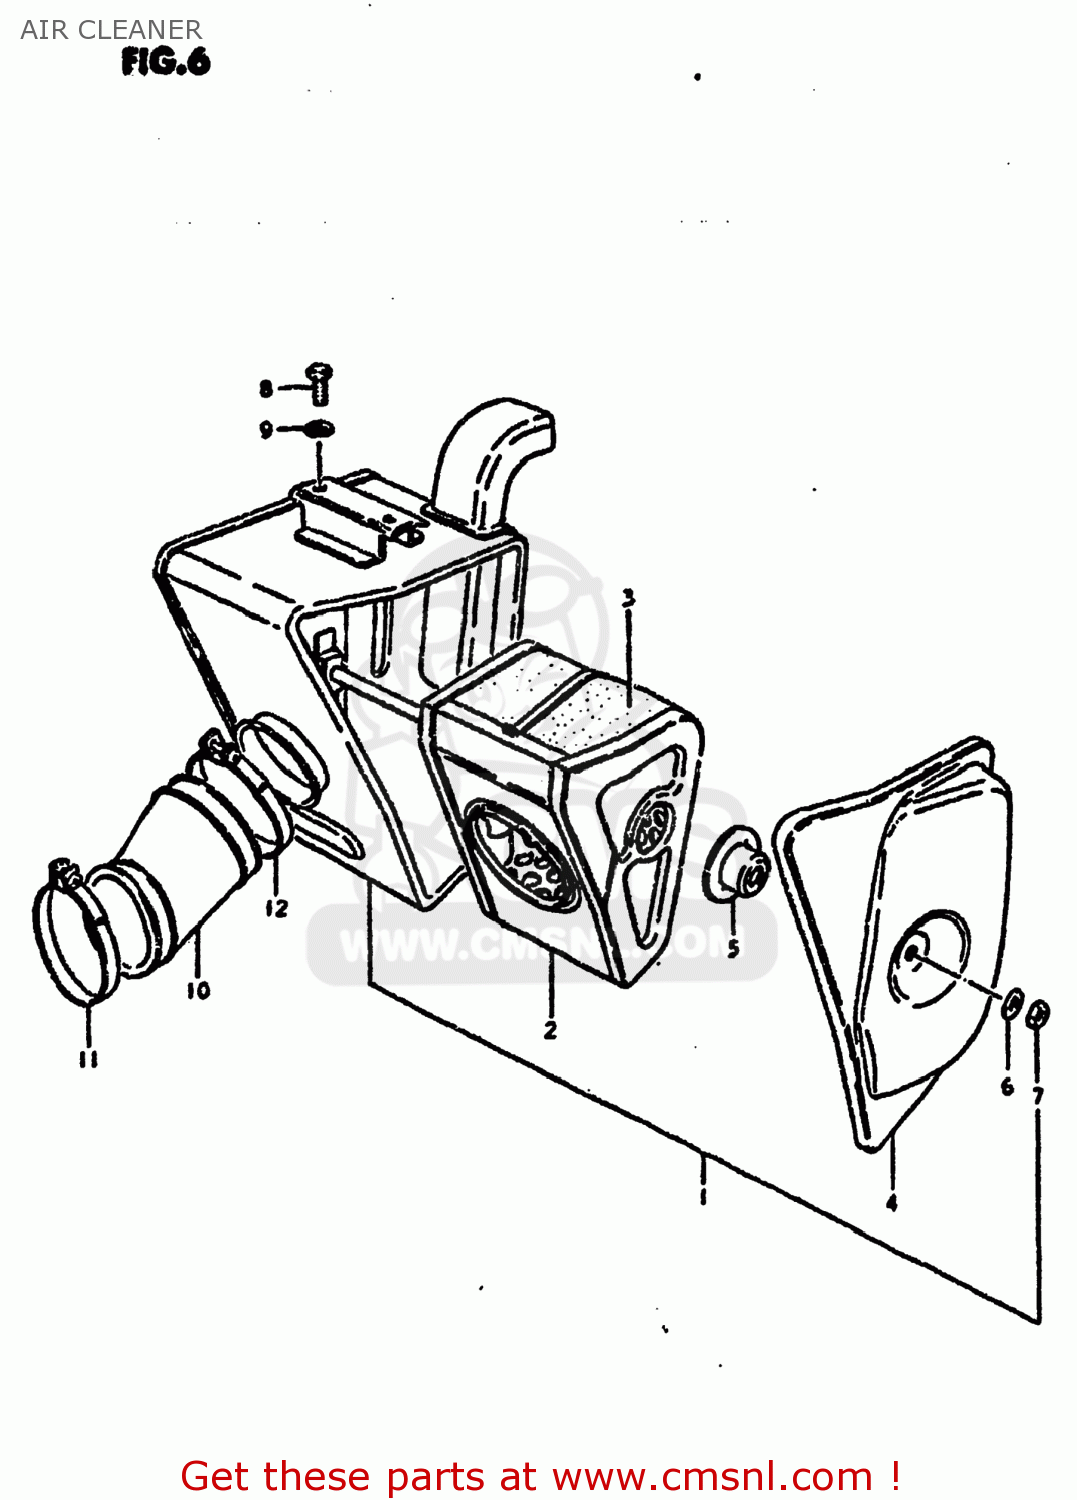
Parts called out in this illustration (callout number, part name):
1	CLEANER ASSEMBLY,AIR
2	FILTER ASSY,AIR CLEANER
3	FILTER
4	CAP
5	SPACER
6	WASHER
7	NUT
8	BOLT
9	WASHER
10	HOSE,CARBURETOR AIR INLET
11	CLAMP
12	CLAMP
